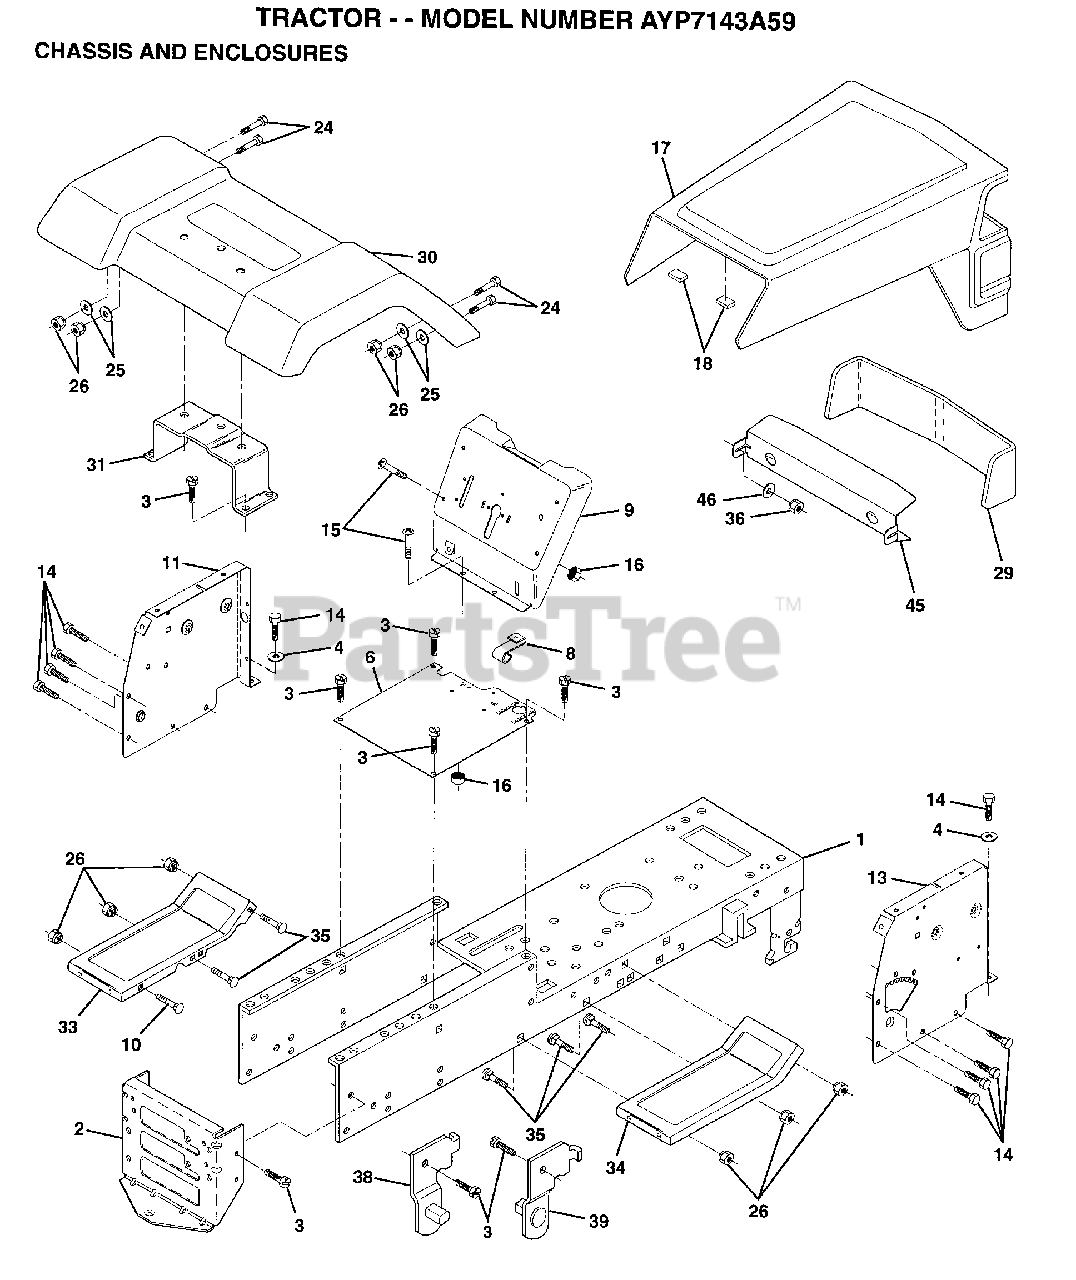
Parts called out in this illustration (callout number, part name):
3	SCREW
4	WASHER
5	LOCKWASHER
8	"CLIP,INSULATOR"
9	DASH SILKSCRN 1
11	DASH PANEL LH
14	SCREW LT
15	SCREW
17	HOOD/GRILL ASM
24	BOLT
25	WASHER
26	NUT
30	FENDER
31	BRKT FENDER
33	FOOTREST LH
34	FOOTREST RH
35	BOLT
36	PAL NUT LT
38	BRACKET ASM LH
39	BRACKET ASM RH
46	RETAINER
